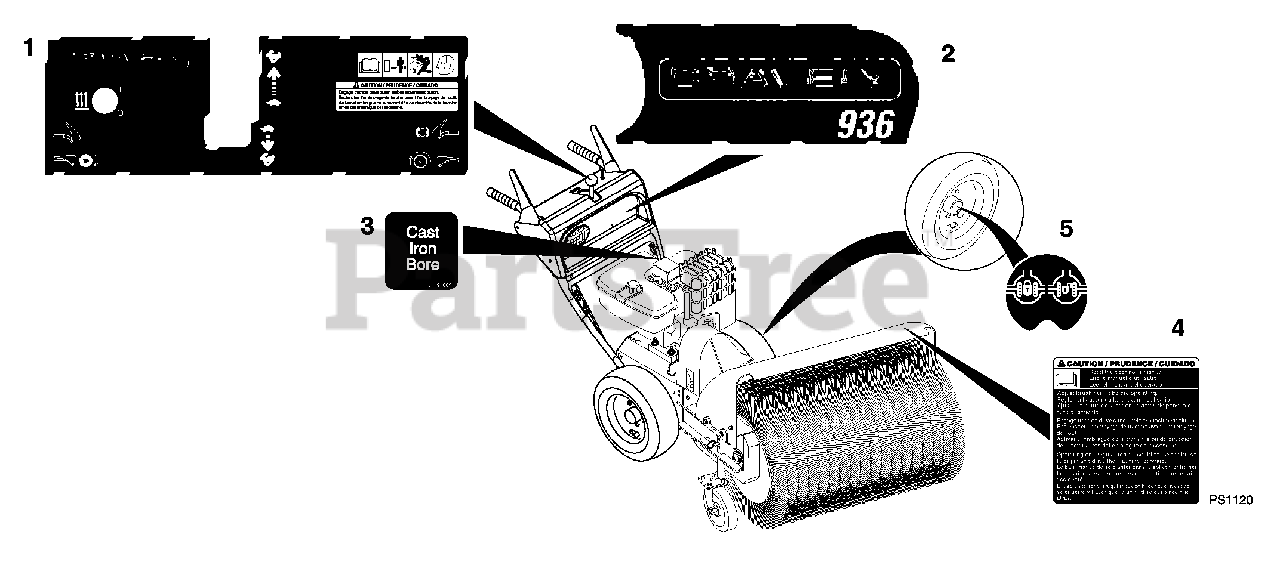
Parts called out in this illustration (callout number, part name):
1	Decal, 936 Control Panel
2	Decal, 936 Dash
3	Decal, Cast Iron Bore
4	Decal, Caution
5	Decal, Differential Lock
